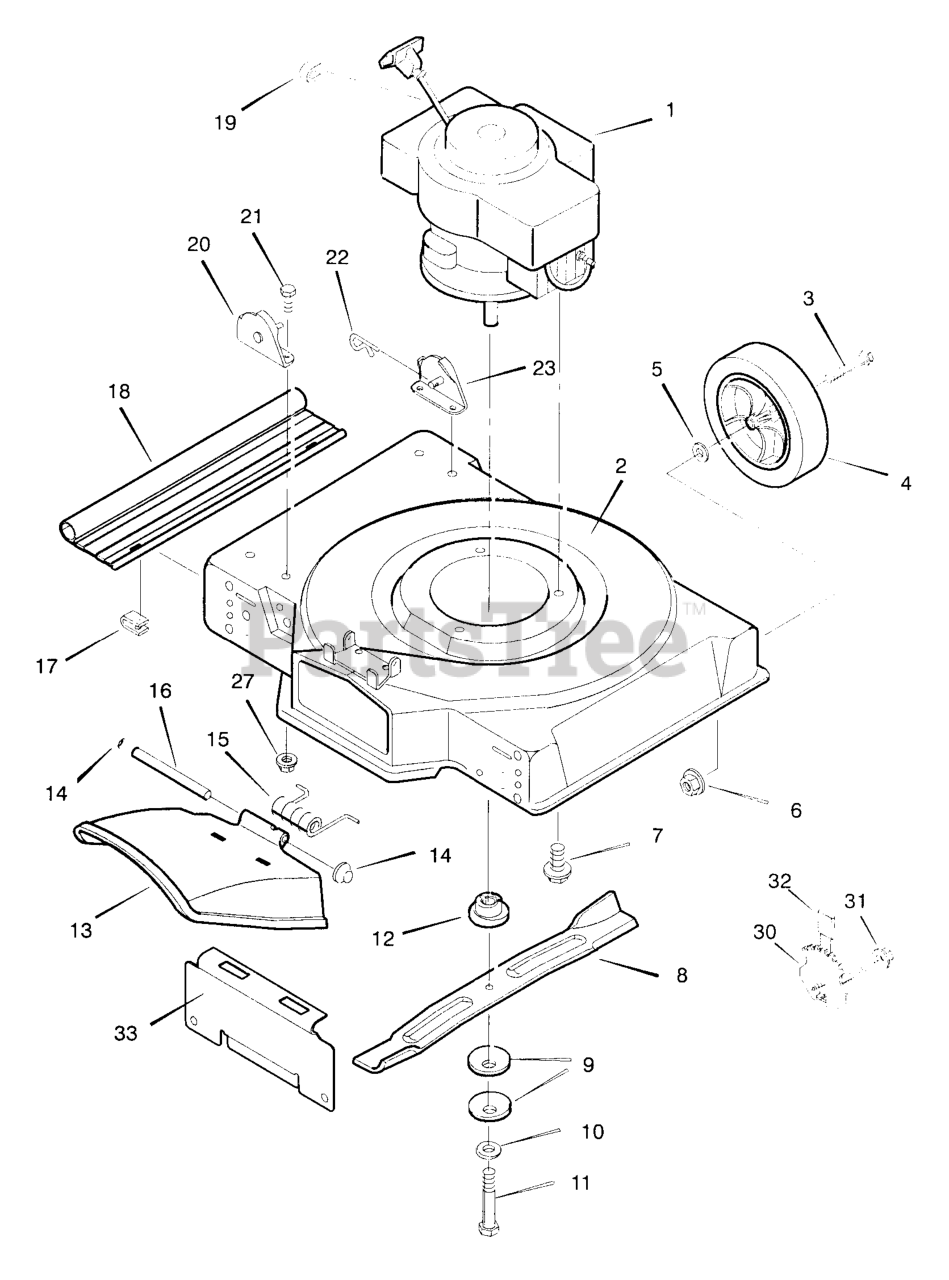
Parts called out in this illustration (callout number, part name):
1	Engine
2	Housing
3	Bolt, Axle
4	Wheel and Tire
6	Locknut, Flange
7	Bolt, Engine
9	Washer, Belleville
11	Bolt, Hex
12	Adapter, Blade
13	Deflector, Chute
14	Push-On Cap
16	Pin, Pivot
17	Retainer
18	Deflector, Rear
19	Stop, Rope
20	Bracket, Right Handle
22	Pin, Hair
23	Bracket, Left Handle
27	Nut
30	Adjuster, Height
31	Locknut, Flange
33	Plate, Mulcher
